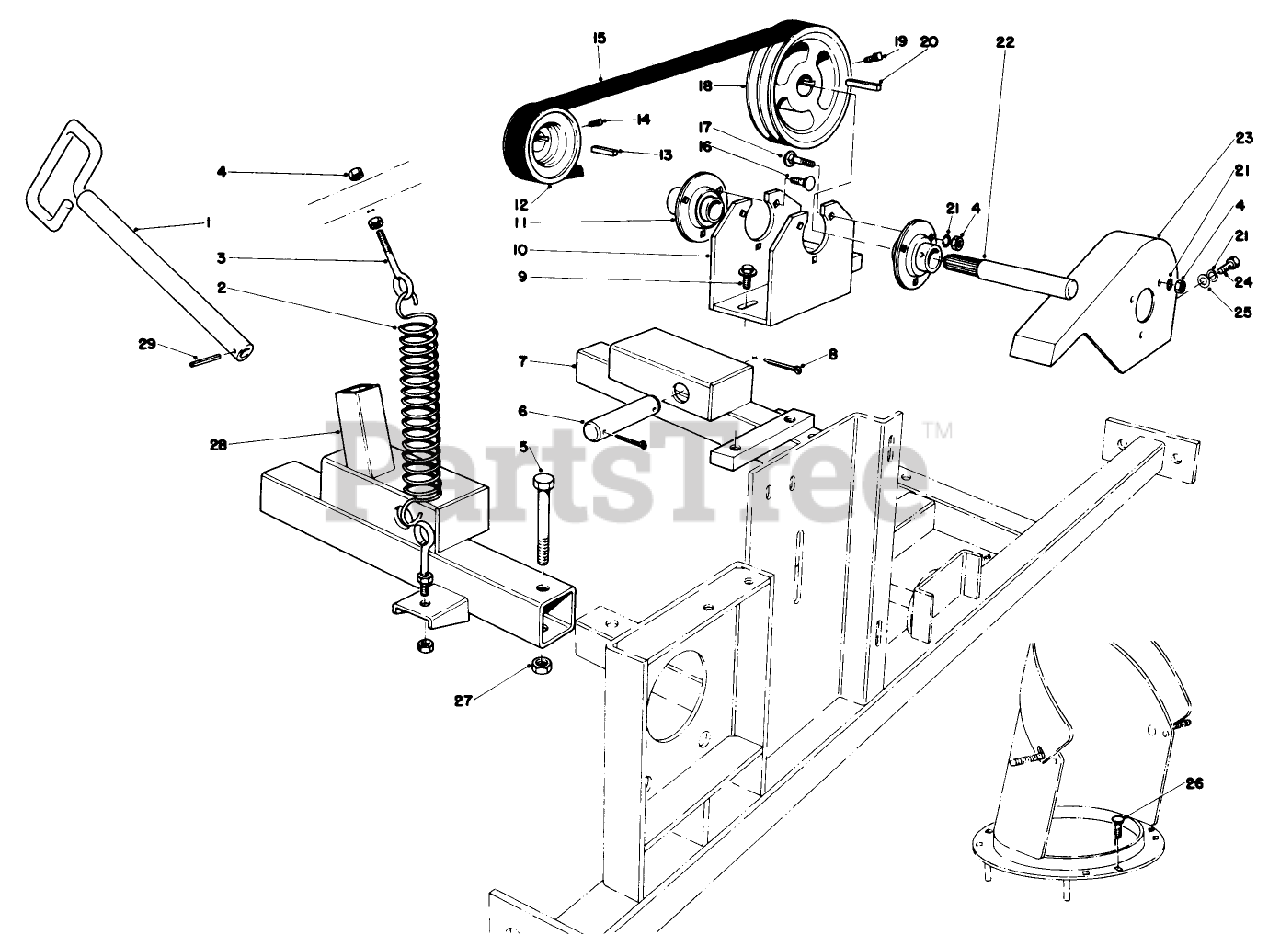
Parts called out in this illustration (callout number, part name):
4	NUT-HEX
5	SCREW-HH
8	3/32 X 1-3/4 LG COTTER
9	SCREW-HHF
13	KEY-SQUARE
14	SCREW-SET, SQH
16	SCREW-CARR
17	BOLT-CARR
19	SCREW-SET, SQH
21	WASHER-LOCK/SP
24	SCREW-HH
25	WASHER-PLAIN
26	SCREW-CARR
27	NUT-LOCK, CONE
29	PIN-SPRING
